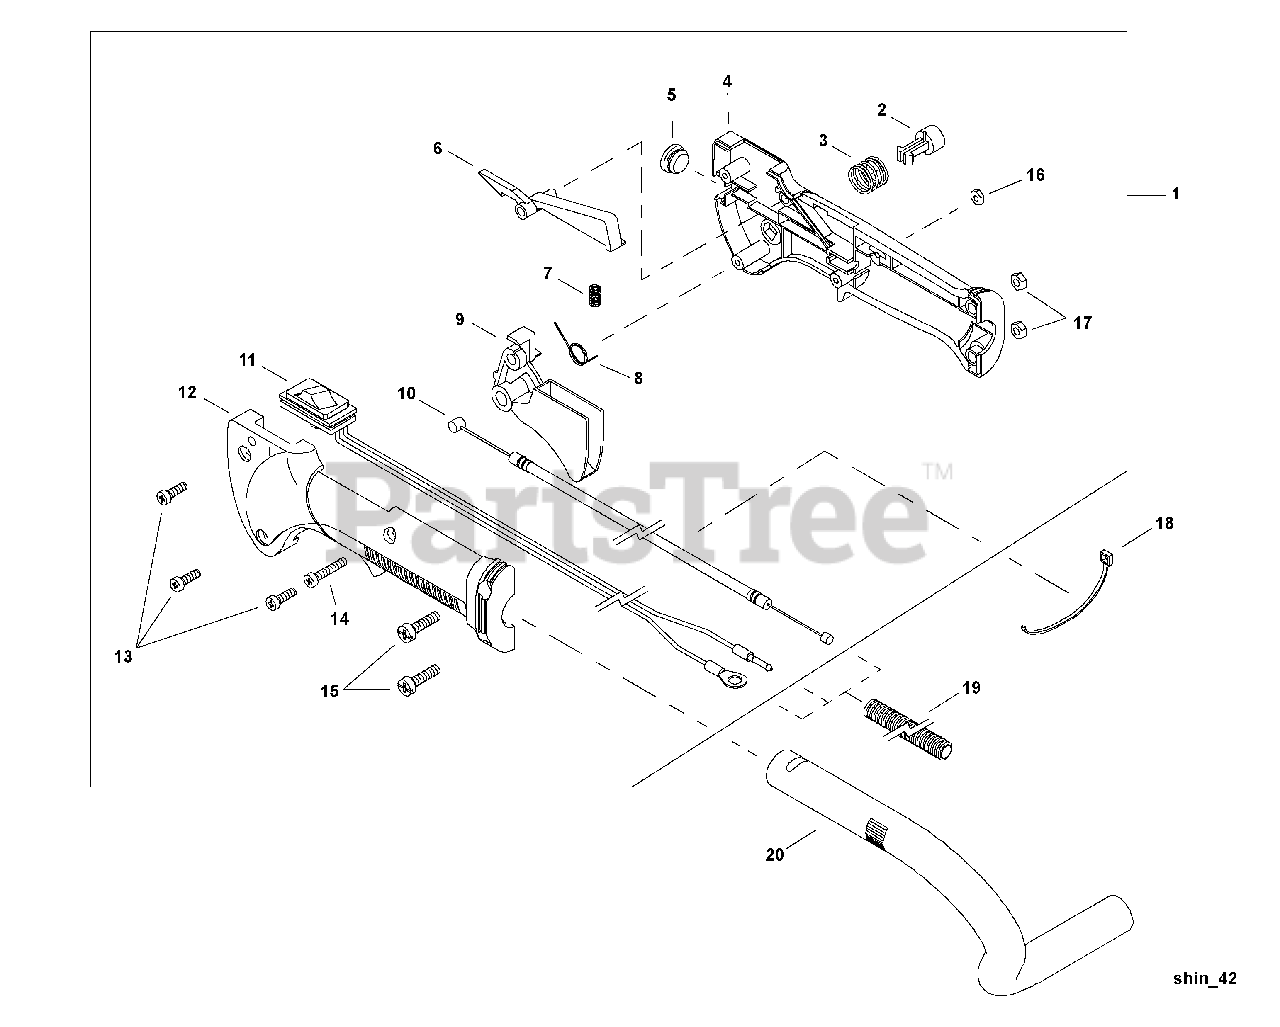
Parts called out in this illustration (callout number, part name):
1	THROTTLE CONTROL ASSY
2	LOCK, THROTTLE
4	HANDLE, CONTROL - RIGHT
6	LEVER, TRIGGER LOCKOUT
8	SPRING, TRIGGER
9	TRIGGER, THROTTLE
10	CABLE, THROTTLE
11	IGNITION SWITCH ASSY
12	HANDLE, CONTROL - LEFT
13	SCREW - 4X16 -- TAPPING
14	SCREW - 4X23
15	SCREW - 5X20
16	NUT - 4
17	NUT - 5
18	TIE, CABLE
19	TUBE, PROTECTIVE - CORRUGATED
20	HANDLE - REAR
